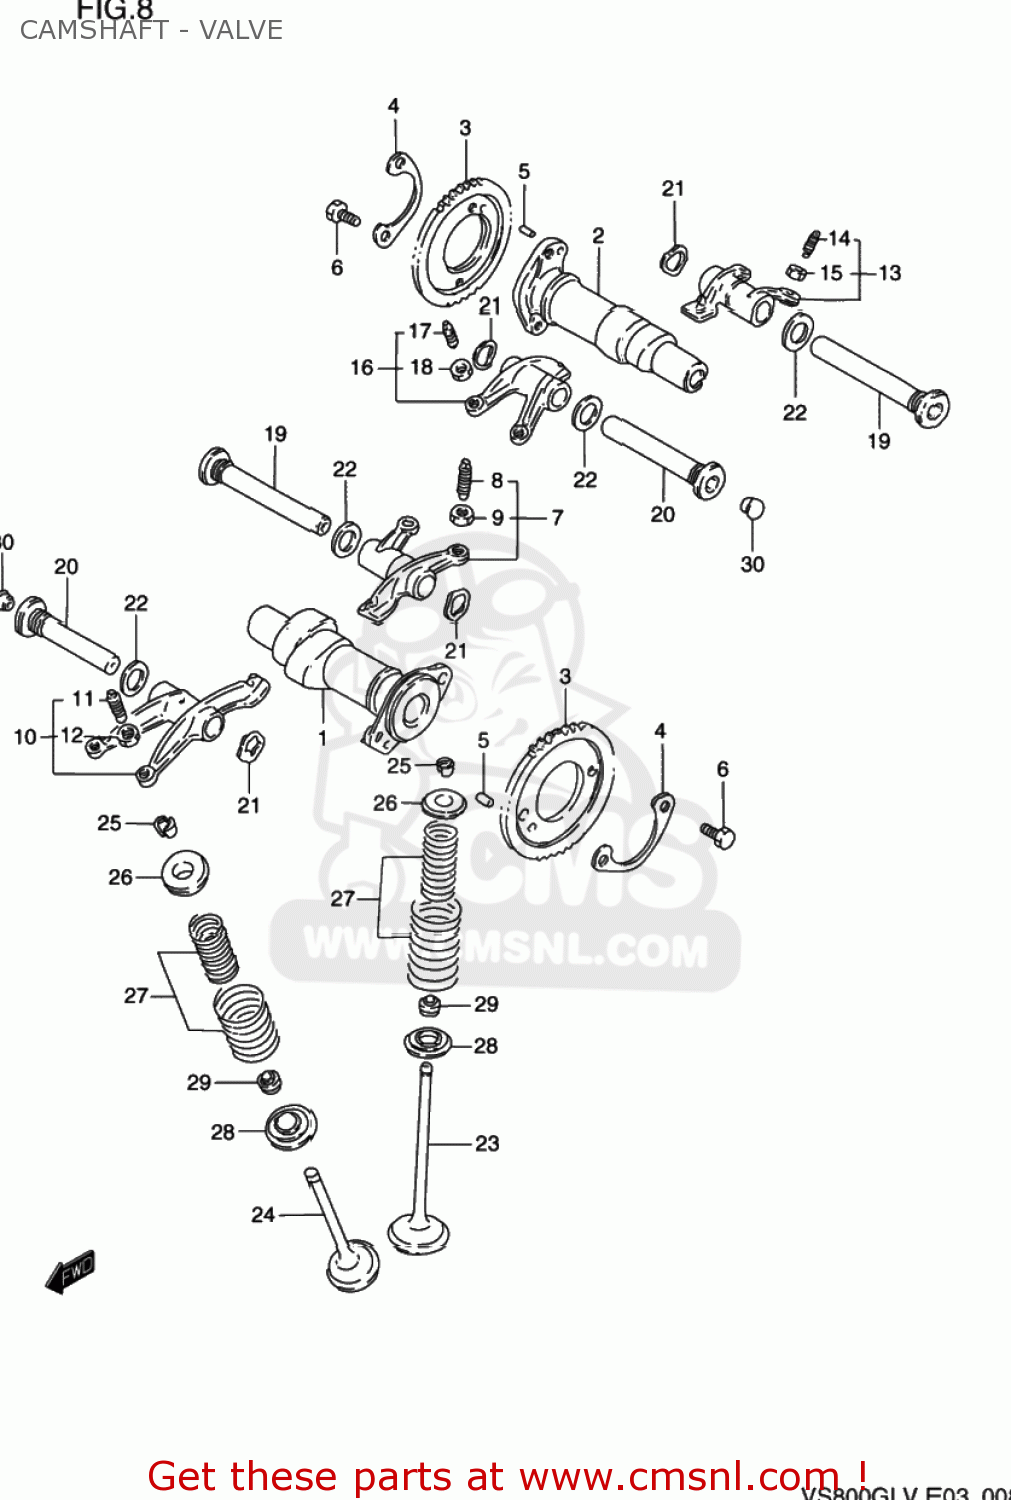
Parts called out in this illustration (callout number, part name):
1	CAMSHAFT,FR
2	CAMSHAFT,RR
3	SPROCKET,CAMSHAFT(NT:42)
4	WASHER,CAM CHAIN SPROCKET
5	PIN
6	BOLT(6X12.5)
7	ARM,INTAKE VALVE ROCKER FR
8	SCREW,TAPPET ADJUSTING
9	NUT,ADJUSTING SCREW
10	ARM,EXHAUST VALVE ROCKER FR
11	SCREW,TAPPET ADJUSTING
12	NUT,ADJUSTING SCREW
13	ARM,INTAKE VALVE ROCKER RR
14	SCREW,TAPPET ADJUSTING
15	NUT,ADJUSTING SCREW
16	ARM,EXHAUST VALVE ROCKER RR
17	SCREW,TAPPET ADJUSTING
18	NUT,ADJUSTING SCREW
19	SHAFT,VALVE ROCKER
20	SHAFT,VALVE ROCKER ARM
21	WASHER
22	GASKET(14X19.2X2) (NAS)
23	VALVE,INTAKE
24	VALVE,EXHAUST
25	COTTER,VALVE
26	RETAINER,VALVE SPRING
27	SPRING SET,VALVE
28	SEAT,VALVE SPRING
29	OIL SEAL
30	CAP(OD:12)
